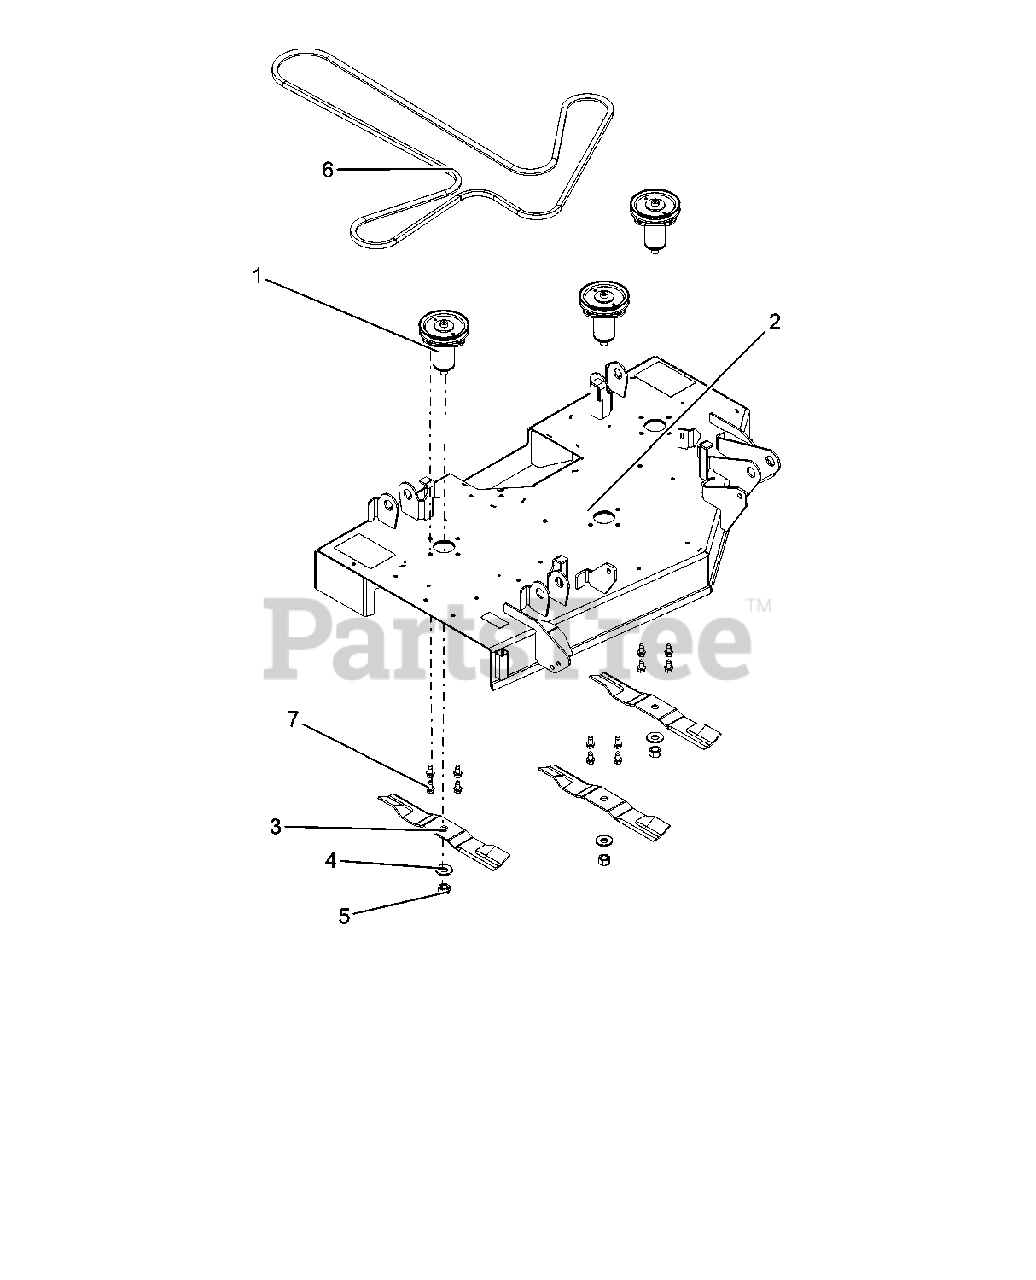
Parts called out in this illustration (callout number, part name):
1	KIT, DECK SPINDLE ASM-IKON-ZTX
2	KIT, 42" ARIENS DECK W/DECALS
3	BLADE, MOWER 15.00"
4	WSHR-BLVL .669X1.535X.138
5	NUT-HEX .62-18 YWZC
6	V-BELT, 4L-WRAPPED
7	@SCR-TAP .38-16X.75 HWH TR YWZ
